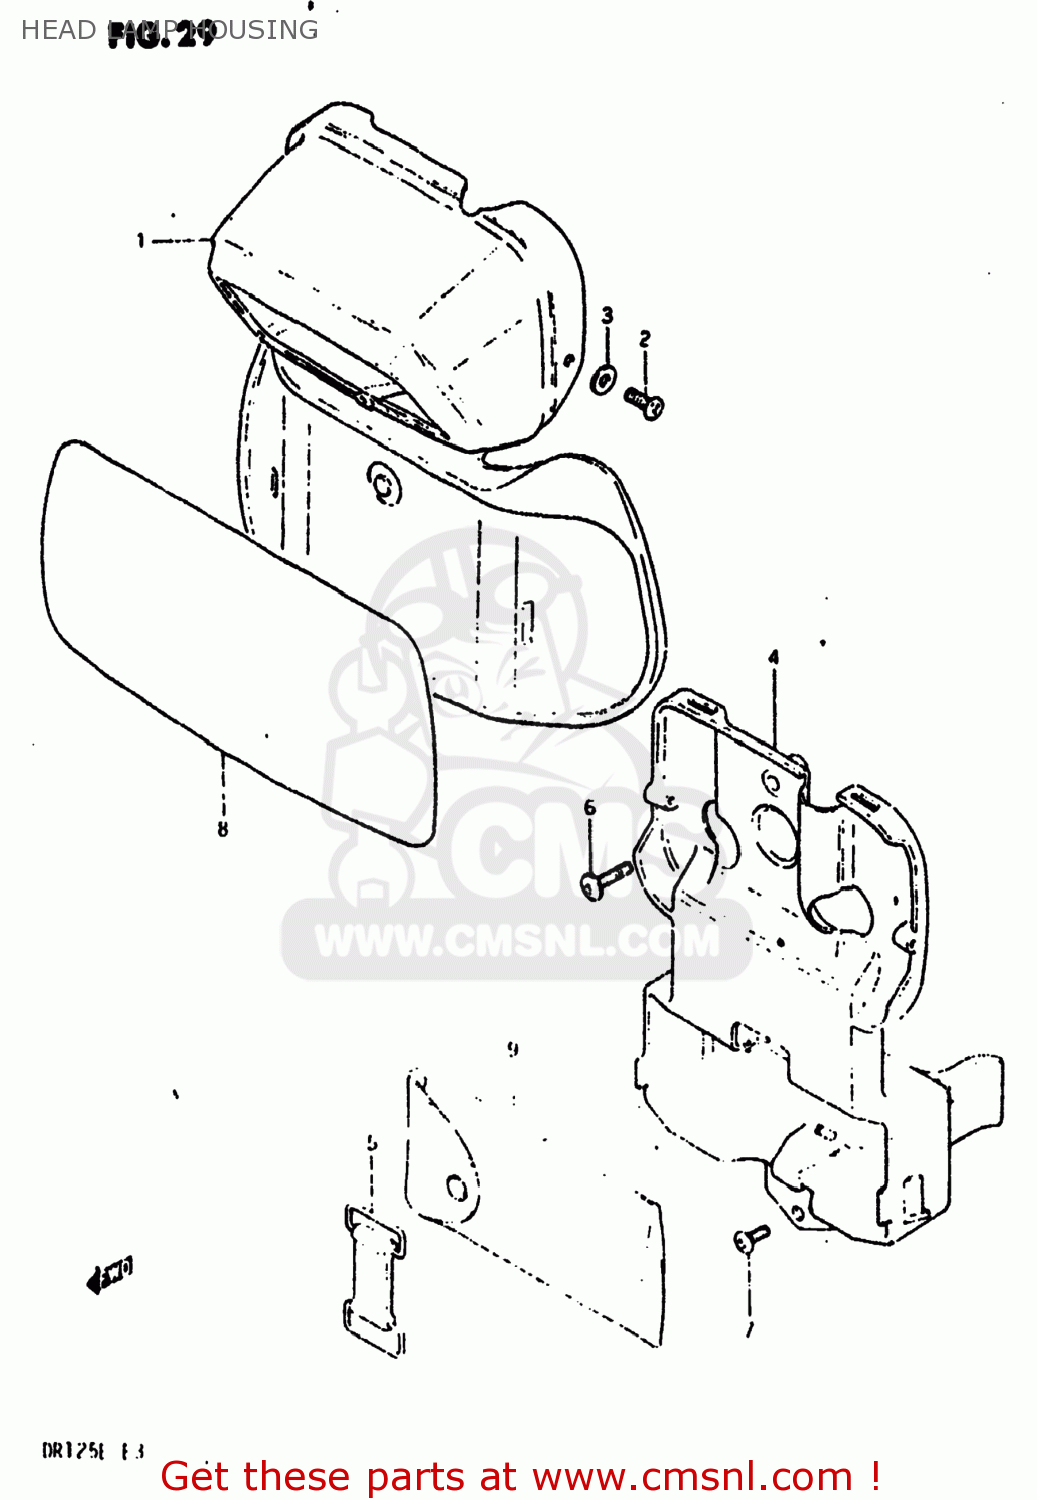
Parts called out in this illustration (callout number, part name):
1	HOUSING,HEADLAMP
2	TAPPING SCREW
3	WASHER
4	HOLDER,TOOL
5	BAND
6	SCREW
7	SCREW
8	EMBLEM,FRONT NUMBER PLATE
9	TOOL SET
